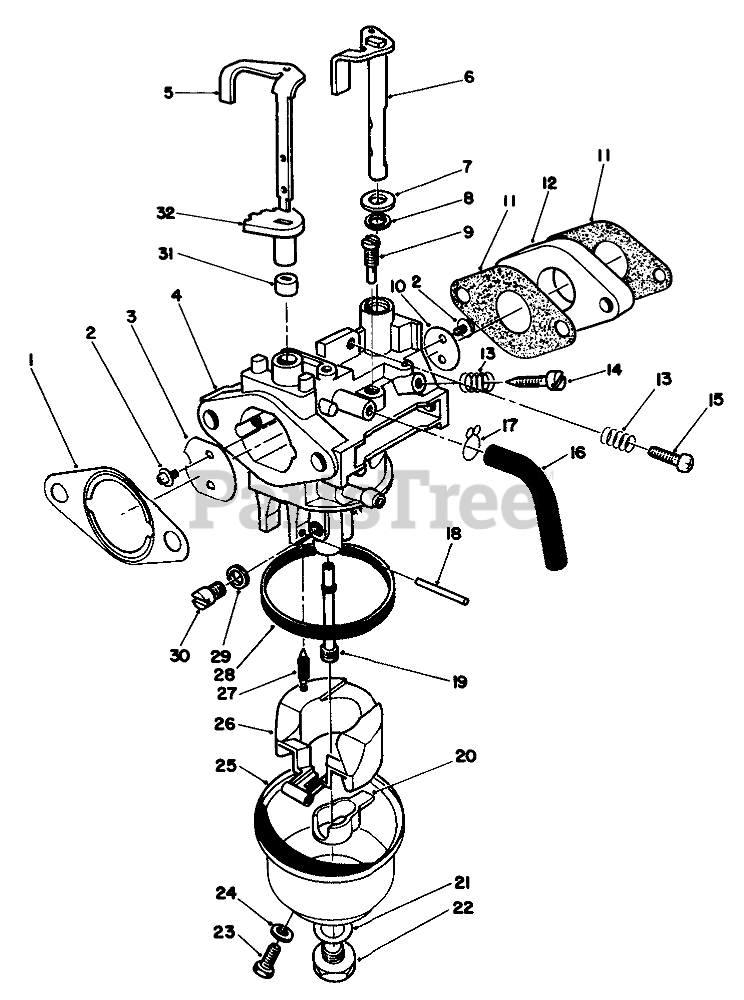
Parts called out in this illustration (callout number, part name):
1	GASKET F/W ENGINE
2	Screw
3	VALVE
4	Body-Carburetor
5	Shaft-Choke Valve (Incl. Ref. No. 31 & 32)
6	SHAFT
7	WASHER
8	Seal-Throttle Shaft
9	PILOT JET
10	VALVE
11	Gasket-Carburetor
12	CARB INSULATOR
13	SPRING-PILOT SCREW
14	ADJUSTER
15	SCREW
17	CLAMP
18	Pin
19	NOZZLE
20	SPACER
21	GASKET
22	SCREW
23	SCREW
24	GASKET
26	FLOAT
27	NEEDLE
28	FLOAT BOWL GASKET
29	SPACER
30	MAIN JET
31	LOWER CHOKE RING
32	UPPER CHOKE RING
